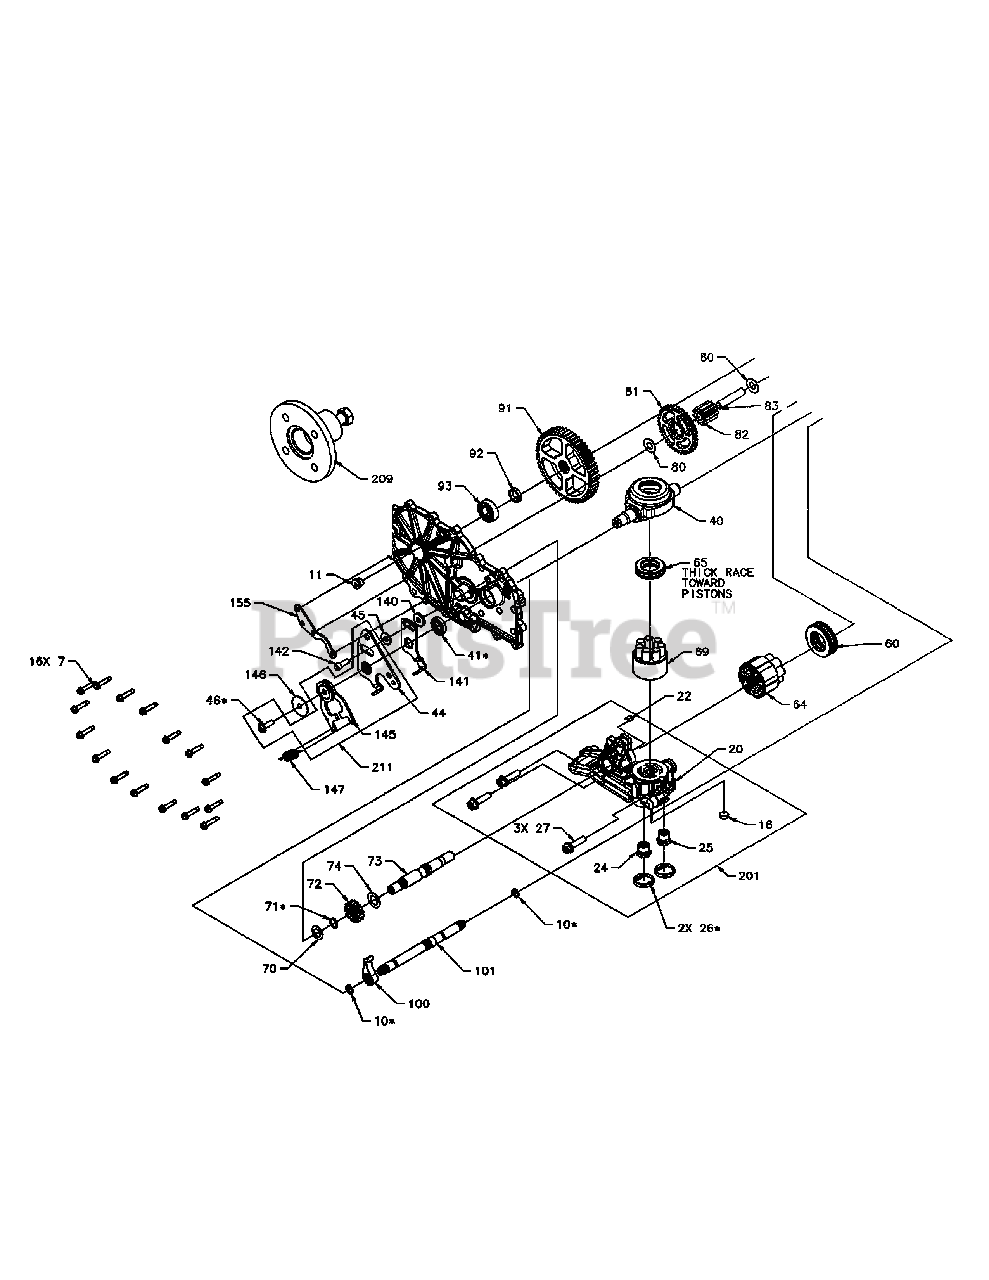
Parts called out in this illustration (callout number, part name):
1	Kit, Housing, Main, LH
2	Kit, Cover, Side, LH, CNTL
7	HFHCS 1/4-20x1.25
10	D-Ring - 111 .103x.424
11	Plug 9/16-18 (Metal)
13	Sealant
14	FLUID-DRIVE SYSTEM, quart
16	Plug, Rubber
20	Center Section, LH
22	Plate, Bypass
23	Filter, Oil
24	Shock Valve
25	Shock Valve
26	Seal, Plug 1.250x.250
27	HFHCS 3/8-16x1.5 (Patch)
30	Seal, Lip .375x.75x.25
31	Ring, Ret .375 External
32	Rod, Bypass
33	Ring, Ret .750 Internal
34	Arm, Bypass
35	Ring, Rtng .375 EXT
40	Trunnion, Swashplate
41	Seal, Lip 18x32x7
44	Arm, Control RH
45	Washer .34x.88x.06
46	TWHCS 5/16-24x1.00 (Patch)
52	Shaft, Input
53	BRG, Ball 17x40x12 Open 6203
54	Ring, Ret Wire .561 ID
55	Washer 1.23x1.56x.04
56	Seal, Lip 17x40x7
57	Ring, Ret 2.06 INT
60	Bearing, Thrust
64	Ass’y, Cylinder Block, 16cc
65	BRG, Thrust Ball 30x52x13
69	Ass’y, Block 7 Piston
70	Washer .63x1.0x.05
71	Ring, Ret 62 EXT
72	Gear, 16T
73	Shaft, Motor
74	Washer .72x1.16x.04
80	Washer .5x1.0x.03
83	Jack Shaft (Pin)
90	Ring, Ret 2.06 INT
92	Spacer, .750x1.000x.257
93	Bearing, Ball, .75x40x12
94	Shaft, Axle
95	BRG, Ball 1.0x52x15 Open 6205M
96	Seal, Lip 25x52x10 TC (Gray)
97	Kit, Hub, 4 Bolt
99	Nut, Hex Lock 3/4-16
100	Pawl, Brake
101	Shaft, Brake
102	Handle, Brake
103	Clip, Retaining
105	HFHCS 1/4-20x.75
106	Guard, Filter, LH
111	Fitting, DSTR 9/16-18 SAE .5 Barb
120	Fan 7’’, 10 Blade
121	Pulley 4.5 Inch
122	Nut, Hex Locking 1/2-20 Nylon
123	HFHCS 1/4-20x.875
130	Tube, Connecting
140	Spacer, .320x.1.5x.062
141	Arm, Nuetral Right
142	SHCS 5/16-24x1 Patch
145	Assembly, RTN
146	Washer, .343x1.5x.062
147	Spring, Extension .57x2
155	Bracket, Damper
200	Kit, Seal
201	Kit, Center Section, LH
207	Kit, Fan/Pulley
209	Hub Puller, 4-Bolt
210	Kit, Input Shaft
211	Kit, RTN, Bidirectional
212	Kit, Axle Shaft
